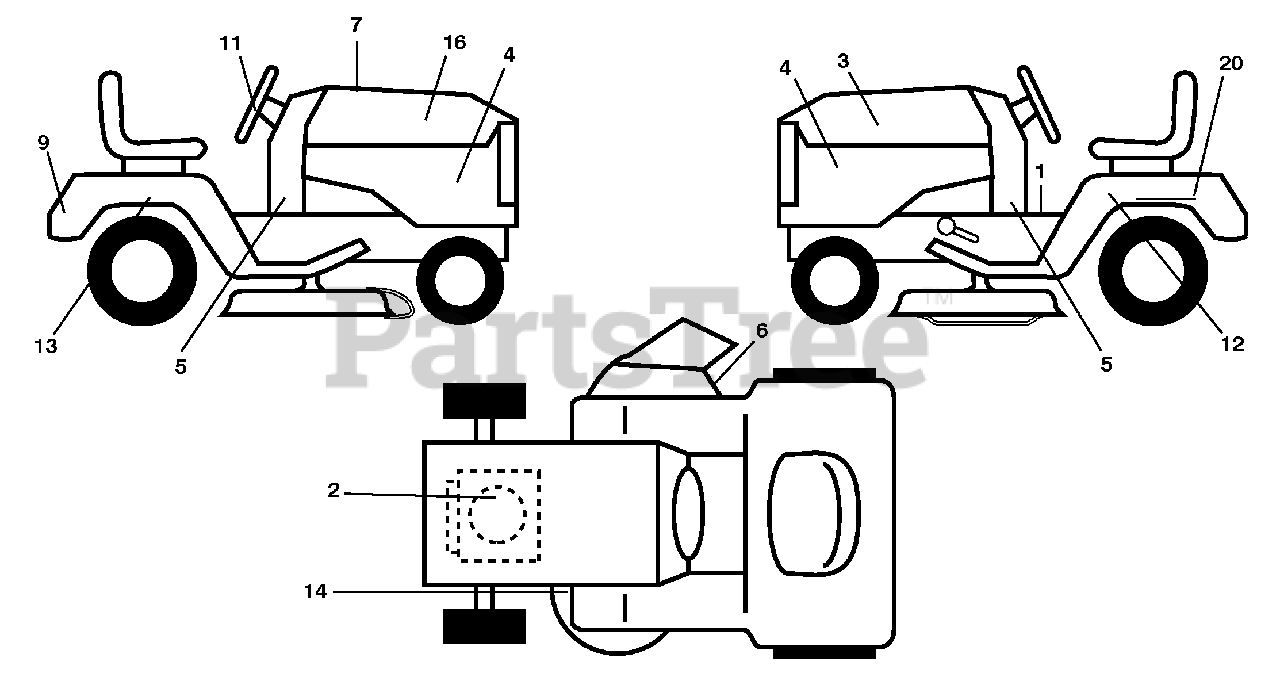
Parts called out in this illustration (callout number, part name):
1	Decal Warning
2	Decal Eng. H.P.
3	Decal Hood LH
4	Decal Side Panel Logo
5	Decal Lwr Dash
6	Decal Warning, Keep Hand Away
7	Decal Replacement Parts
9	Decal Fender Logo
11	Decal Ins Strg Whl
12	Decal Fend SD LH
13	Decal Fend SD RH
14	Decal V-Belt Schematic
16	Decal Hood Rh
20	Decal Bat Dan/Psn
20	Pad Footrest LH
20	Pad Footrest RH
20	Manual Operator's (Eng/French)
20	Manual Parts (Eng/French)
